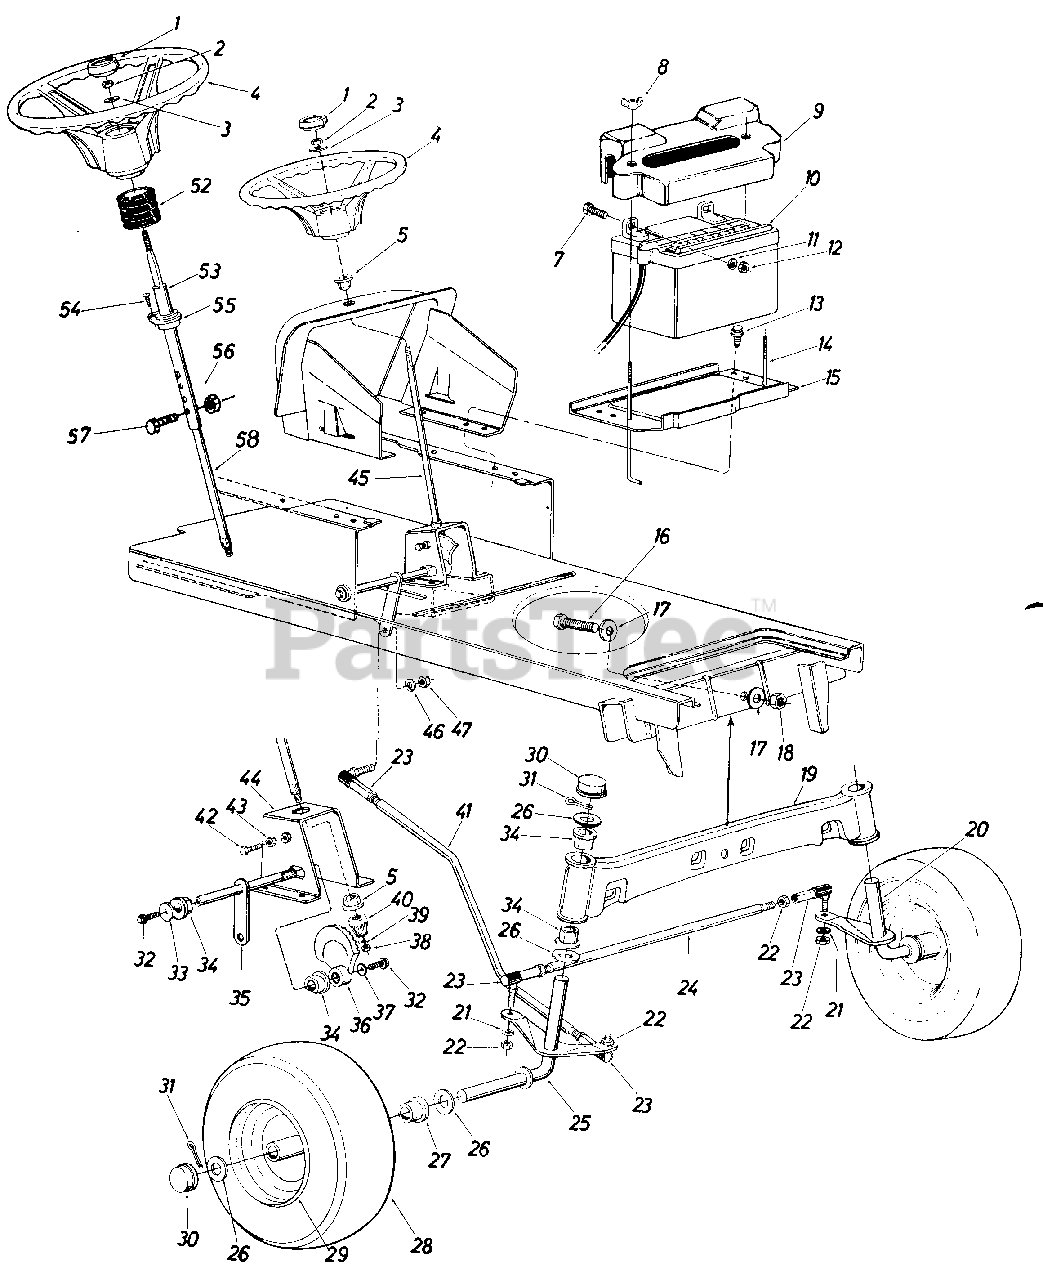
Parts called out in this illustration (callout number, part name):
1	Steering Wheel Cap
2	Hex Cent. L-Nut 5/16-18 Thd.
3	Bell-Wash. 5/16" I.D. x .87" O.D. x .060
4	Steering Wheel
5	Plastic Hex Bearing 518" I.D.
7	Hex Scr 1/4-20 x .62" Lg.
8	Wing Nut Plastic 1/4-20 Thd.
9	Battery Cover
10	12-V Battery
11	L-Wash. 1/4" I.D.
12	Hex Nut 1/4-20 Thd.*
13	Hex Thd. Rolling Scr. 1/4-20 x.50" Lg.
14	Battery Hold Down Rod
15	Battery Plate
16	Hex Scr. 5/8-18 x 2.50" Lg.
17	Flat Wash. .66" I.D. x 2.25" O.D. x .17
18	Hex Cent. L-Nut 5/8-18 Thd.
19	Front Pivot Bar Ass'y.
20	Front Axle Ass'y.-L. H .
21	L-Wash. 3/8" Scr.
22	Hex Nut 3/8-24 Thd.
23	Ball Joint Ass'y.
24	Tie Rod
25	Front Axle Ass'y.-R . H .
26	Fl-Wash. .780 I.D. x 1.59 O.D.
27	Flange Bearing
28	Front Wheel Ass'y. Comp.
29	Front Wheel Rim Only
30	Dust Cover
31	Cotter Pin 5132" Dia. x 1.00" Lg.*
32	Hex Scr. 3/8-24 x .75" Lg. Grade 5
33	Fl-Wash. 3/8 I.D. x 1.25 O.D. x .090
34	Flange Double "D" Brg. .753 I.D.
35	Steering Arm Shaft Ass'y.
36	Side Gear-Steering
37	Bell-Wash. 3/8" I.D.
38	Hex Cent. L-Nut 5/16-24 Thd.
39	Fl-Wash. 5/16" I.D. x .62 O.D x .059
40	Pinion Gear-Steering
41	Drag Link
42	Hex Nylon Scr. 3/8-16 x 1.25' Lg.
43	Hex Nut 3/8-16 Thd.*
44	Steering Gear Sup. Ass'y.
45	Steering Shaft
46	L-Wash. 3/8" Scr.
47	Hex Nut 3/8-24 Thd.
52	Steering Bellow
53	Upper Steering Shaft
54	Oval Hd. Cr.-Sunk Scr. #10 x 5/8" Lg.
55	Fl-Bearing .89" I.D. x 1.36" O.D.
56	Hex L-Nut 1/4-20 Thd.
57	Hex Bolt 1/4-20 x 1.31" Lg.
58	Lower Steering Shaft
